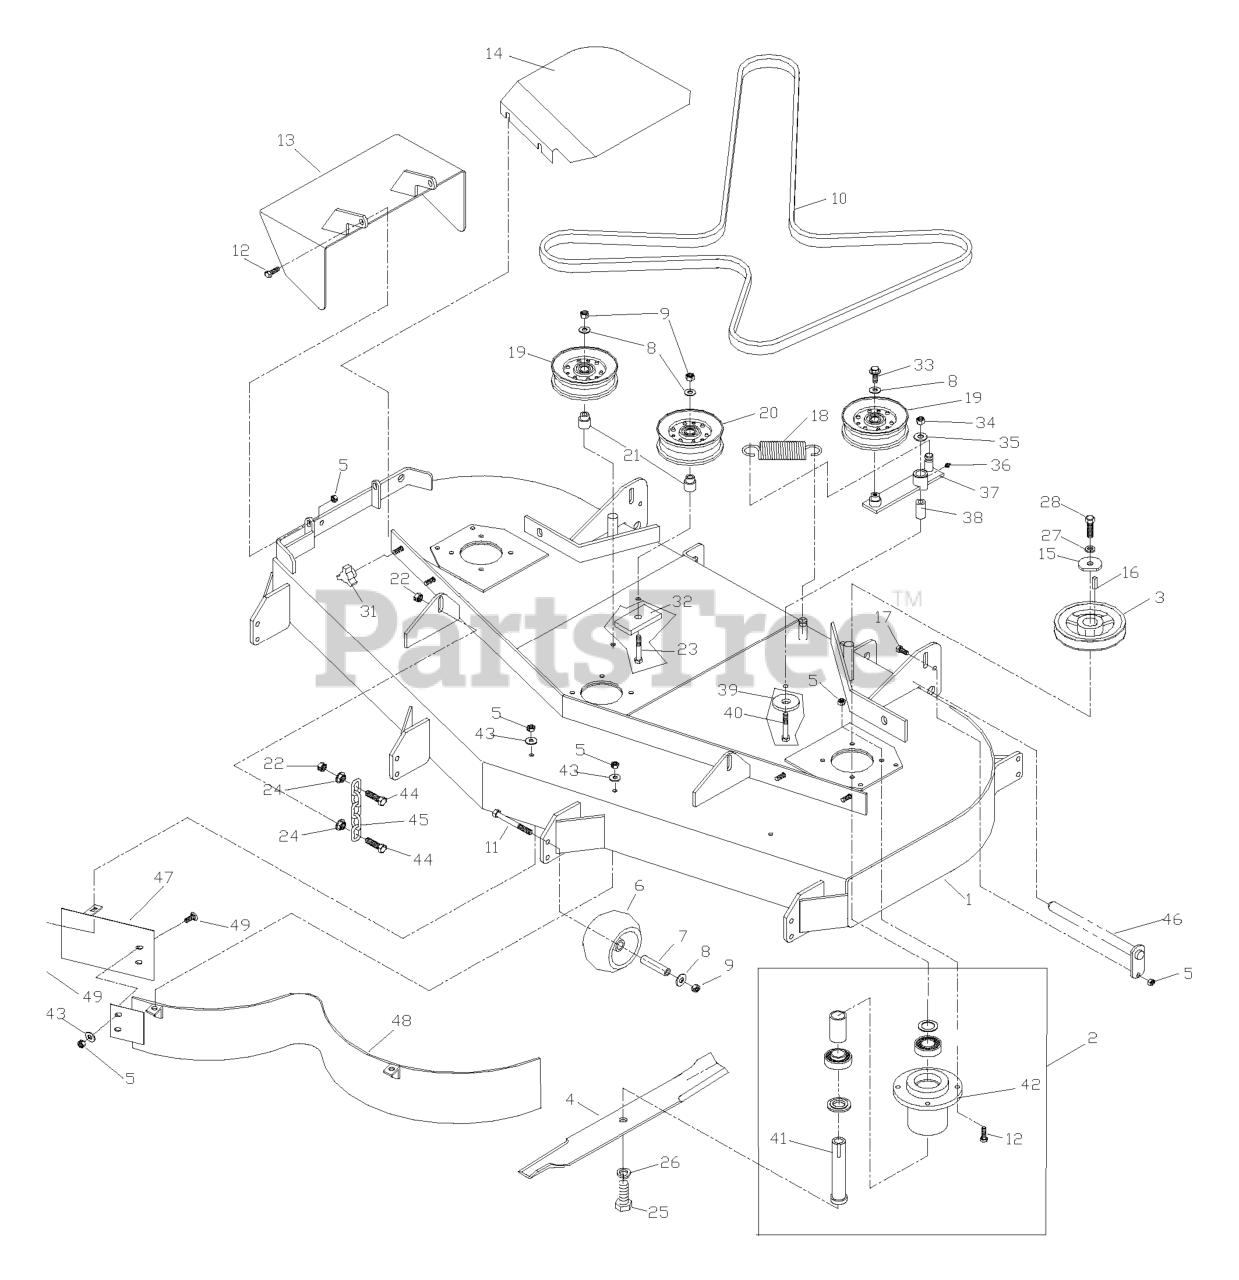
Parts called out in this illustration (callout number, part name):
1	DECK W/DECALS 61" HUS
2	HOUSING ASM.
2	BEARING KIT
4	BLADE OEM 21" (61" DECK)
5	NUT 5/16C CENTERLOCK
6	ANTI-SCALP ROLLER
8	WASHER 3/8 FLAT
9	NUT 3/8C CENTERBLOCK
10	DECK BELT 61
11	HCS 3/8C X 3 1/2
12	HCS 5/16C X 1
13	DISCHARGE CHUTE
14	61 B.S.PAINTED, RT
14	61 B.S.PAINTED, LT ORANGE
15	SPINDLE WASHER
16	KEY 1/4 SQ X 1 1/8
17	HCS 5/16C X 3/4
18	DECK SPRING
19	IDLER PULLEY
20	IDLER PULLEY (TALL)
21	IDLER BUSHING
22	NUT 7/16C CENTERLOCK
23	HCS 3/8C X 2 1/2
24	NUT 7/16C WHIZ
25	HCS 5/8F X 1 1/4
26	LOCKWASHER 5/8
27	WASHER 7/16 LOCK
28	HCS 7/16F X 1 1/2
31	KNOB, THREE PRONG
32	SUPPORT PLATE
33	4CS 3/8C X 1 SERRATED HEAD
34	NUT 1/2-13 HEX NYLOC ZD
35	WASHER 1/2 FLAT
36	ZERK
38	PIVOT BUSHING
39	WASHER, SUPPORT
40	HCS 1/2C X 3 1/4
42	HOUSING, DIE CAST
43	WASHER 5/16 FLAT
44	HCS 7/16C X 1 1/2
45	LIFT CHAIN
47	CENTER BAFFLE - 61
48	MAIN BAFFLE - 61" BLK
49	CARRIAGE BOLT 5/16C X 5/8"
